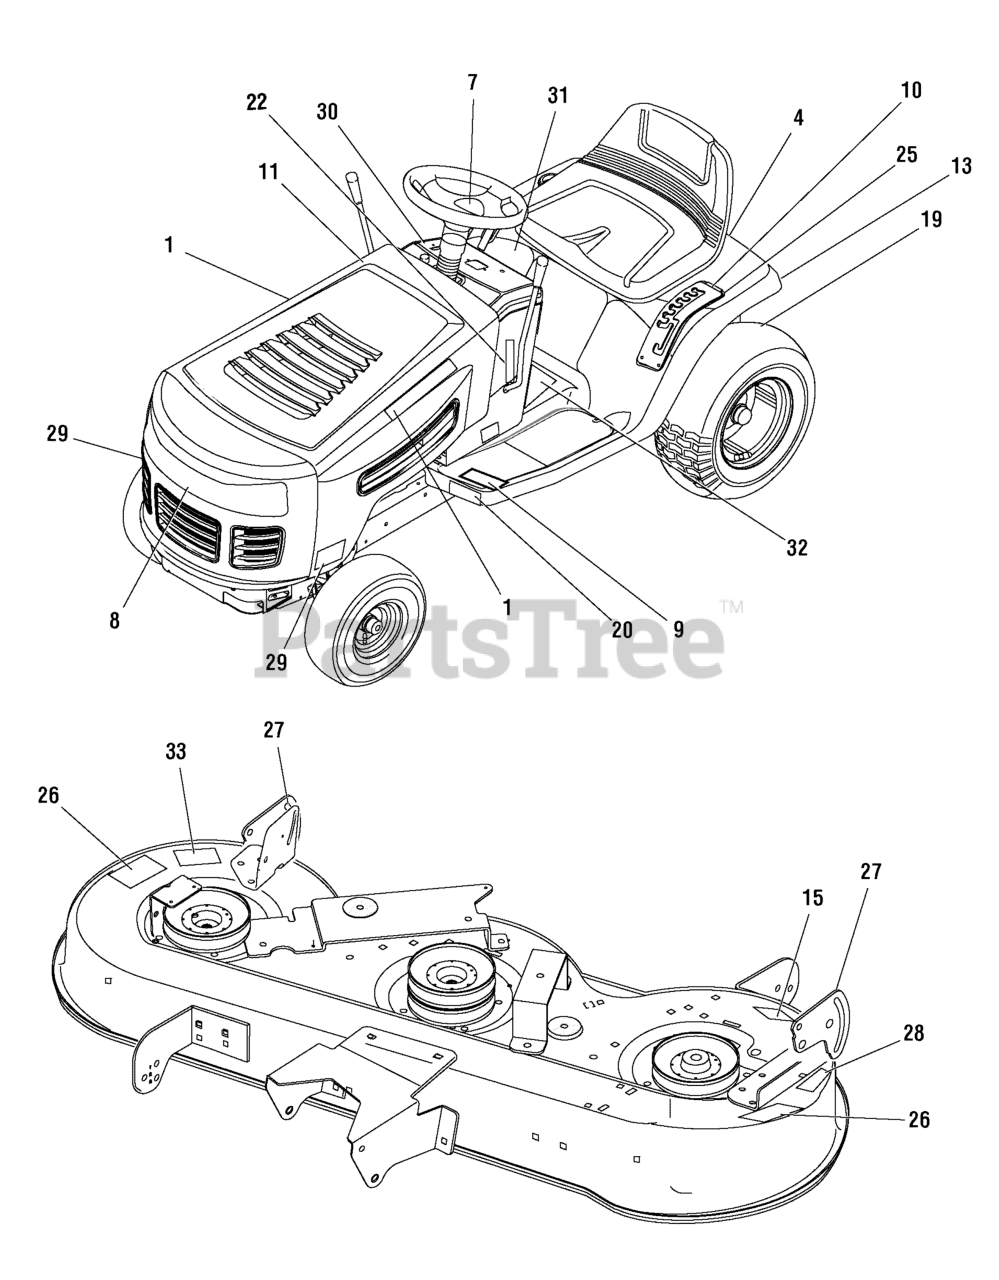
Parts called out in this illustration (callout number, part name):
1	DECAL, Logo, Side Hood
4	DECAL, Murray, Rear
7	DECAL, Steering Wheel
8	DECAL, Front Hood
9	DECAL, Belt/ Clutch
10	DECAL, Deck Level
11	DECAL, Cut Height, 7 Position
13	DECAL, Roll Release
15	DECAL, No Step
19	DECAL, Weight Limitation
20	DECAL, Drive Pedal
22	DECAL, Gas Gauge
25	DECAL, Deck Level
26	DECAL, Danger Do Not Operate w/o Deflector
27	DECAL, Gage, Wheel Leveling
28	DECAL, Gage Wheel Instructions
29	DECAL, MT100
30	DECAL, Dash/ Symbols
31	DECAL, 24HP
32	DECAL, Umber
33	DECAL, Deck Width 117cm
